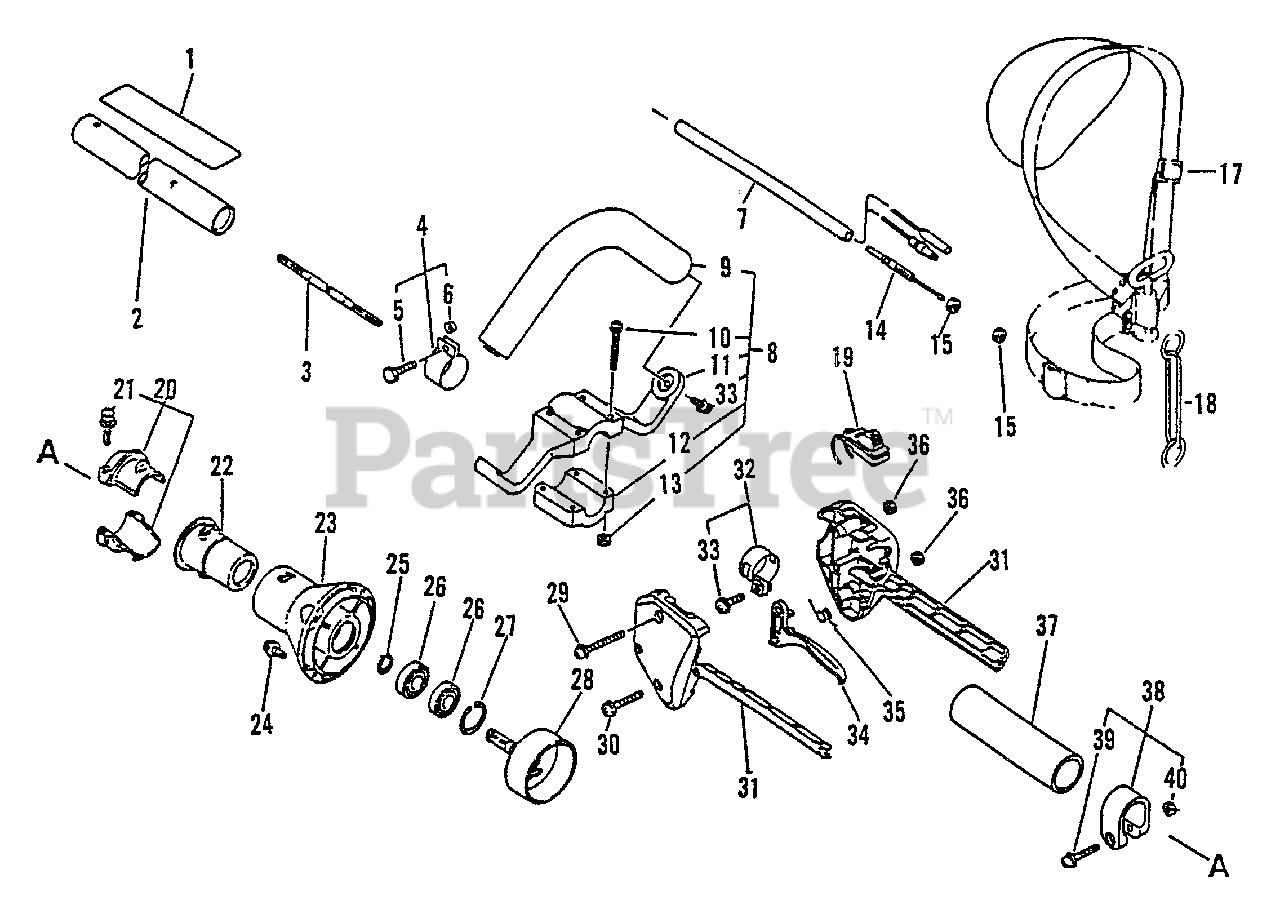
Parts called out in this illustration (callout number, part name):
1	LABEL - CAUTION
2	MAIN PIPE ASSY
3	DRIVESHAFT - SOLID
4	HOOK
5	BOLT - 5X18
7	TUBE - VINYL
8	HANDLE ASSY
9	HANDLE - FRONT
10	SCREW - 5X35
11	BRACKET, HANDLE - UPPER
12	BRACKET, HANDLE
14	CABLE, THROTTLE
17	SHOULDER STRAP ASSY
19	IGNITION SWITCH ASSY
20	HOLDER KIT
21	BOLT - 5X25
23	CASE, CLUTCH
24	SCREW - 5X16
25	RING, RETAINING - 12
26	BEARING, BALL - 6001
27	RING, RETAINING - 28
28	DRUM, CLUTCH
29	SCREW - 5X35
30	SCREW - 5X25
31	THROTTLE BRACKET SET
32	MAIN PIPE CLAMP KIT
33	SCREW - 5X14
34	TRIGGER, THROTTLE
35	SPRING, TRIGGER
37	GRIP, HANDLE
38	CLAMP
39	SCREW - 5X30
